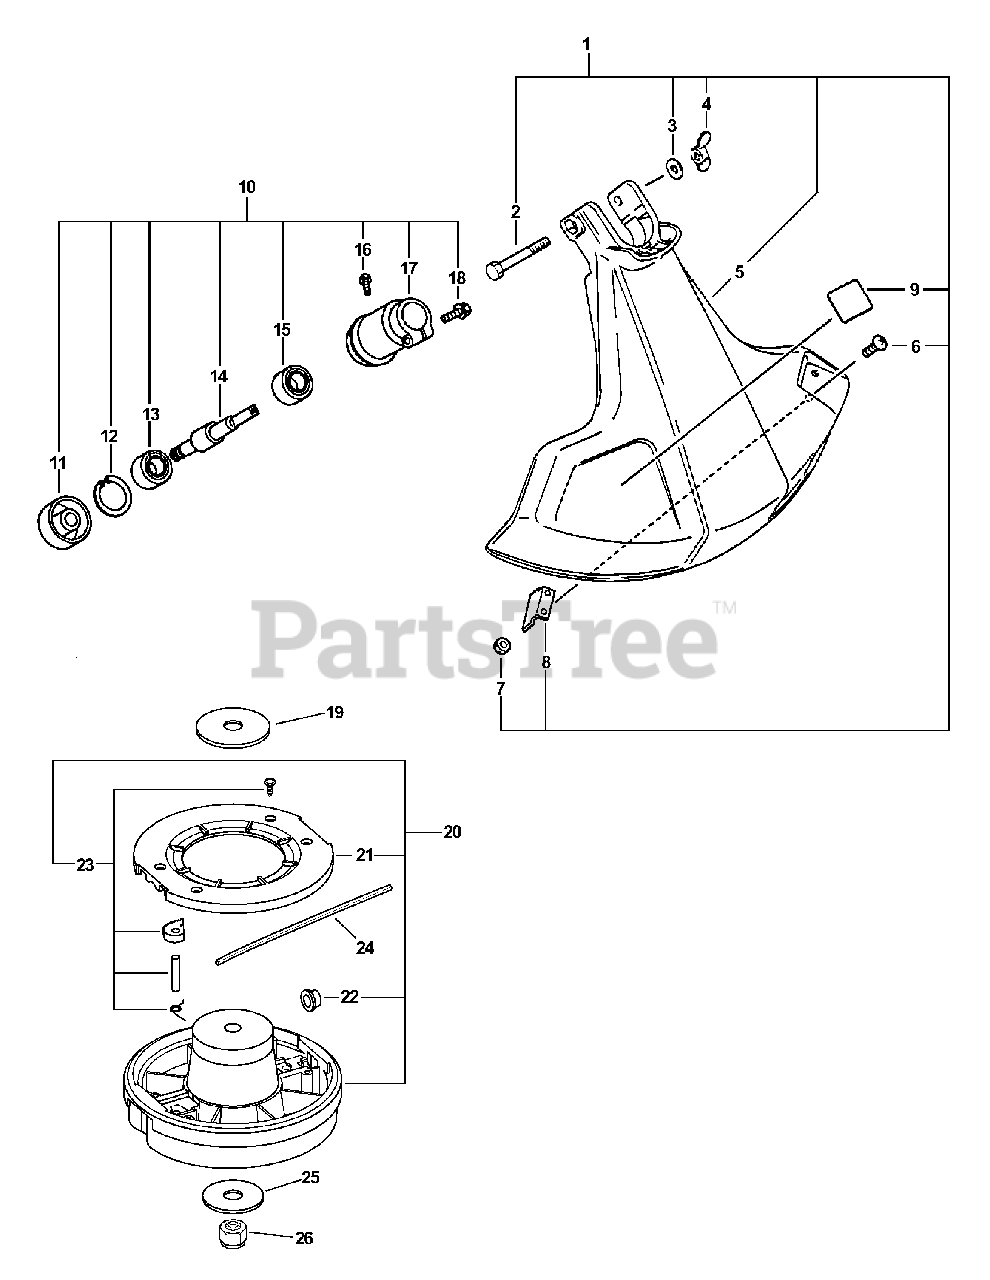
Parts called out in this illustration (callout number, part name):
1	DEBRIS SHIELD KIT
2	BOLT - 1/4-20 X 2"
3	WASHER - 1/4"
4	WINGNUT - 1/4-20
5	SHIELD, DEBRIS - PLASTIC
6	SCREW - 5X16
8	KNIFE, TRIMMER LINE
9	LABEL - CAUTION
10	GEAR CASE ASSY
11	ADAPTOR, BLADE - UPPER
12	RING, RETAINING - 30
13	BEARING, BALL - 6201
14	GEAR - SHAFT
15	BEARING, BALL - 6200
16	SCREW - 4X10
17	CASE, GEAR
18	BOLT - 5X25
19	WASHER - 10
20	TWO LINE RAPID LOADER ATTACHMENT
21	COVER - TOP
23	REPAIR KIT
24	LINE, CUTTING - 0.80" (20 PER PACKAGE)
25	WASHER - 8
26	LOCKNUT
